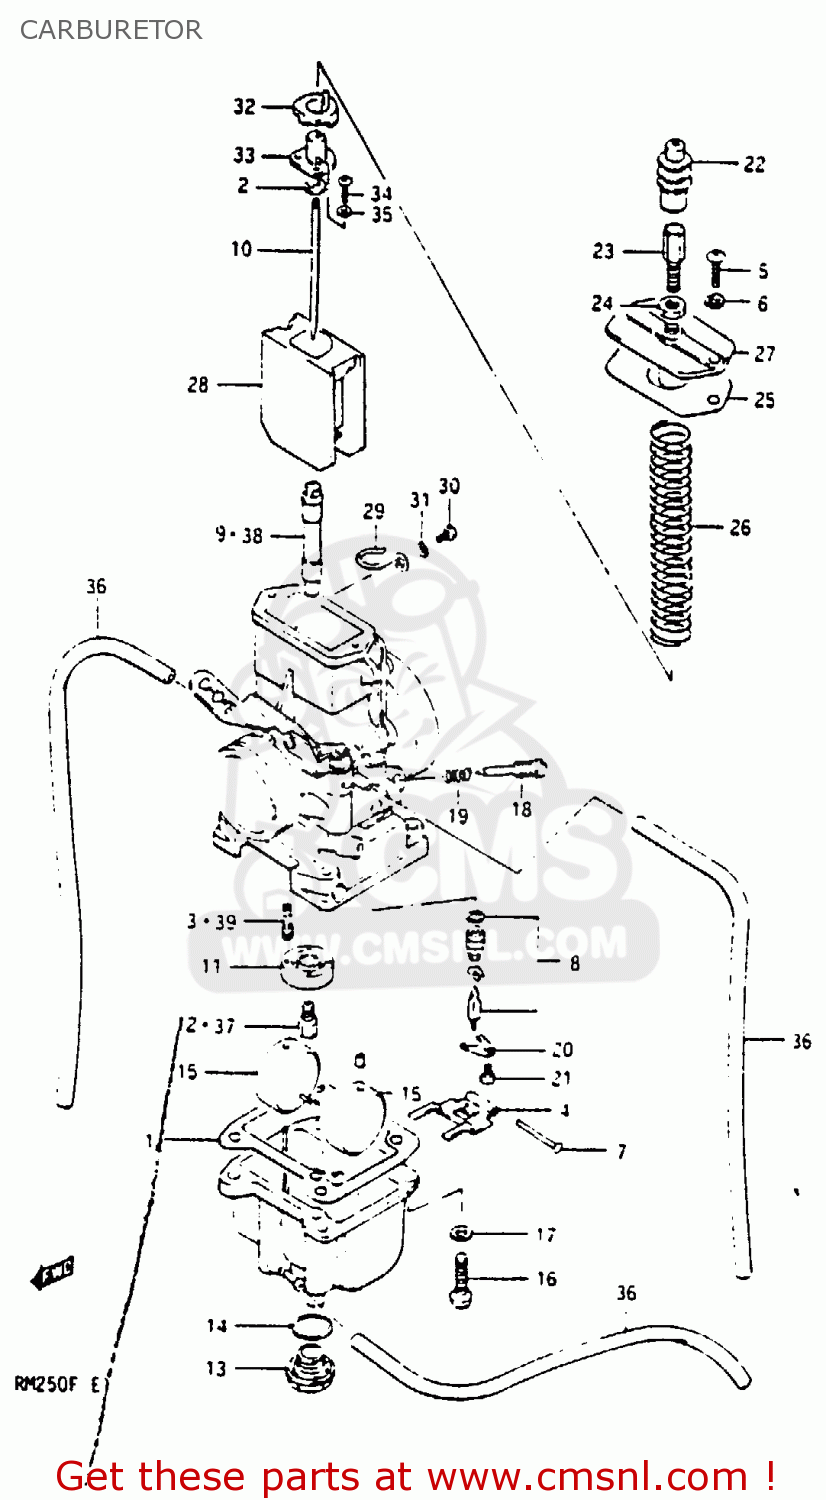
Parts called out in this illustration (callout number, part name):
1	GASKET,FLOAT CAHMBER (NAS)
2	CLIP
3	JET,PILOT(50)
4	ARM,FLOAT
5	SCREW
6	LOCK WASHER
7	PIN,FLOAT
8	VALVE ASSEMBLY,NEEDLE
9	JET,NEEDLE
10	NEEDLE,JET
11	RING,MAIN JET FIXING
12	JET,MAIN(320)
13	SCREW,GUIDE
14	O RING,DRAIN PLUG
15	FLOAT
16	SCREW 5X20
17	LOCK WASHER
18	SCREW,PILOT AIR
19	SPRING
20	PLATE
21	SCREW 4X6
22	CAP,CABLE ADJUSTER
23	ADJUSTER,CABLE
24	NUT
25	GASKET,MIXING CHAMBER (NAS)
26	SPRING,THROTTLE VALVE
27	CAP,CARBURETOR,TOP
28	VALVE,THROTTLE
29	CLIP
30	SCREW
31	LOCK WASHER
32	SEAT,RETURN SPRING
33	PLATE,NEEDLE JET
34	SCREW
35	LOCK WASHER
36	HOSE
37	JET,MAIN(300)
38	JET,NEEDLE
39	JET,PILOT
